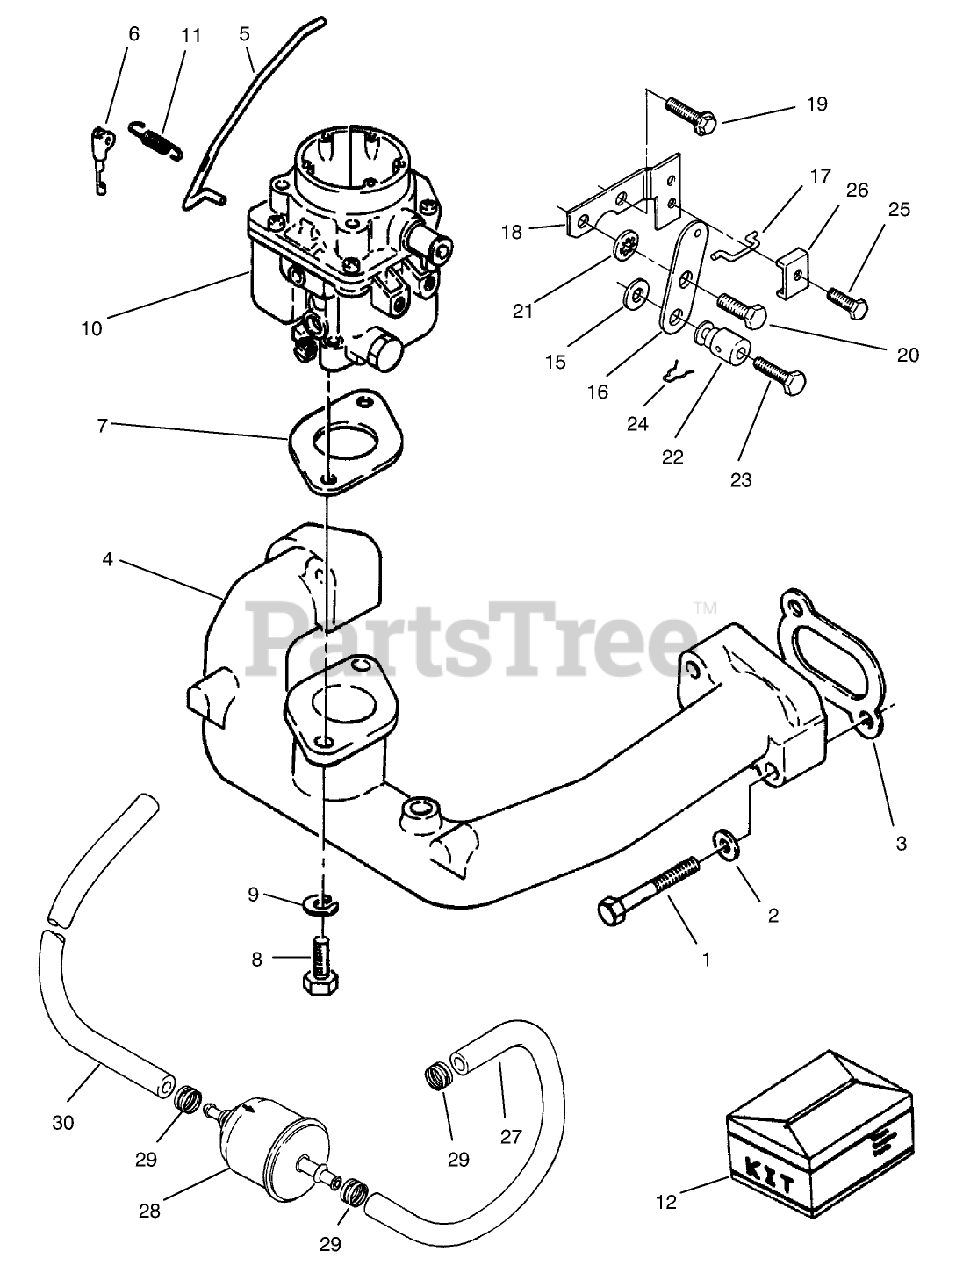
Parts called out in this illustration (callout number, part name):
2	Nut-M8
3	Gasket
4	INTAKE-MANIFOLD
5	GOVERNOR-CONTROL ROD
6	CONTROL-ROD CLIP
7	Gasket
8	HEX-HEAD CAP SCREW
9	Washer
10	COMPLETE-CARBURETOR
11	SPRING
12	Kit-Repair
15	Washer
16	SWIVEL-CHOKE
17	LINK-CHOKE
18	BRACKET
19	Bolt
20	BOLT-SHOULDER
21	Lockwasher
22	SWIVEL
23	Bolt
24	PIN-COTTER
25	Bolt
27	Hose
28	Filter-Fuel
29	Clamp
30	Hose
